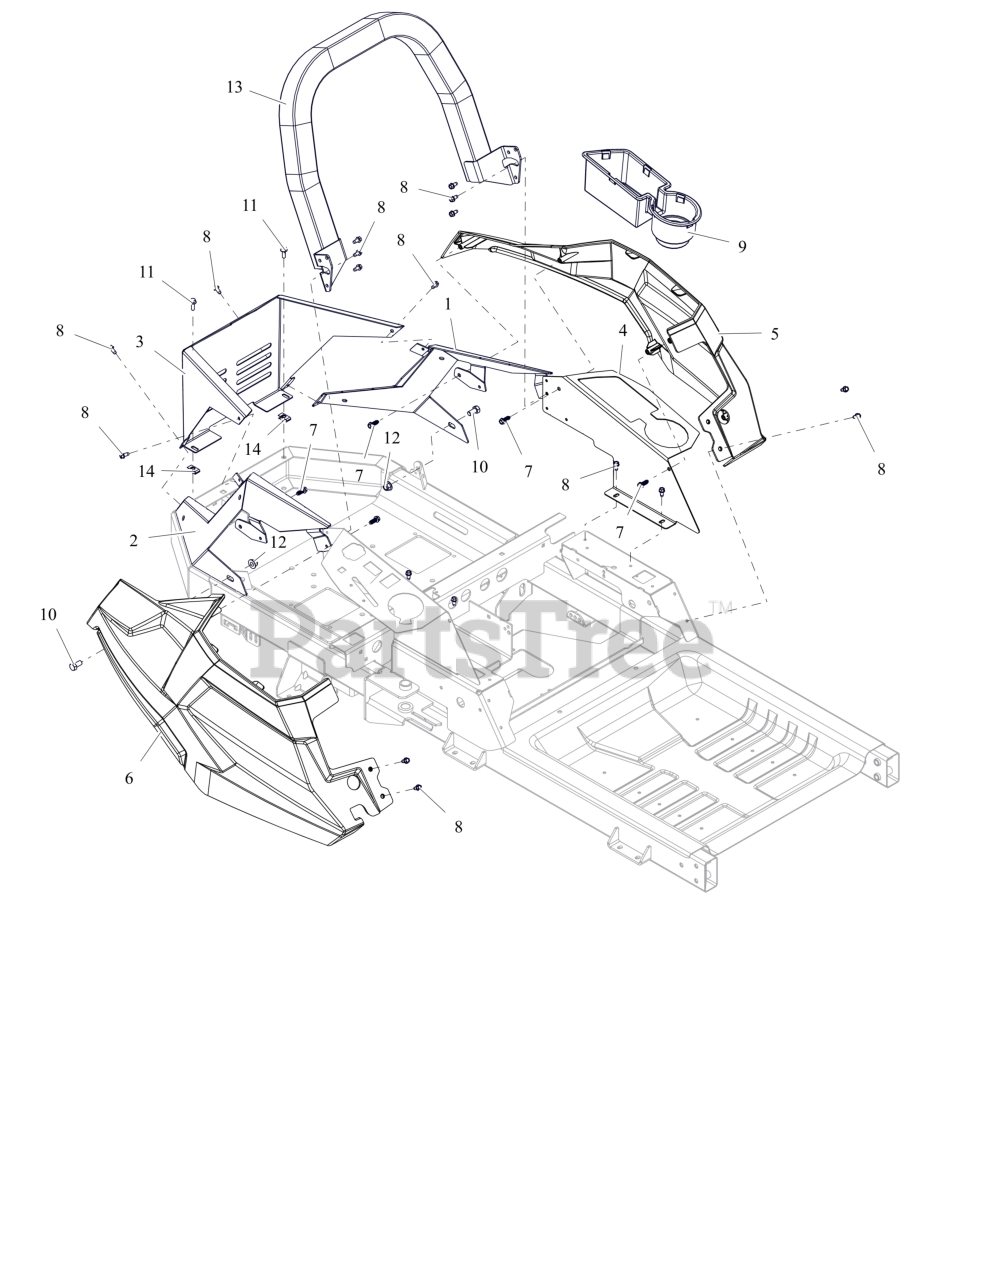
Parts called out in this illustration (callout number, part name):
1	WRAP- REAR - LH
2	WRAP- REAR - RH
3	WRAP, REAR (BLACK)
4	PANEL- CUP HOLDER
5	FENDER, LH
6	FENDER, RH
7	SCR-.312X.75 #14H H/W/H H/L CZ
8	SCR-TAP .25-20X.50 HWH ZCC
9	INSERT, CUP/STORAGE HOLDER
10	BLT,HEX .38-16X.75 G5 ZCC
11	BLT,HEX-FLG .25-20X.75 G5 BFP
12	NUT,NYL-FLG .38-16 GF ZCC
13	WLDMT- ENGINE TOP GUARD
14	NUT-RTNR .25-20X.56
